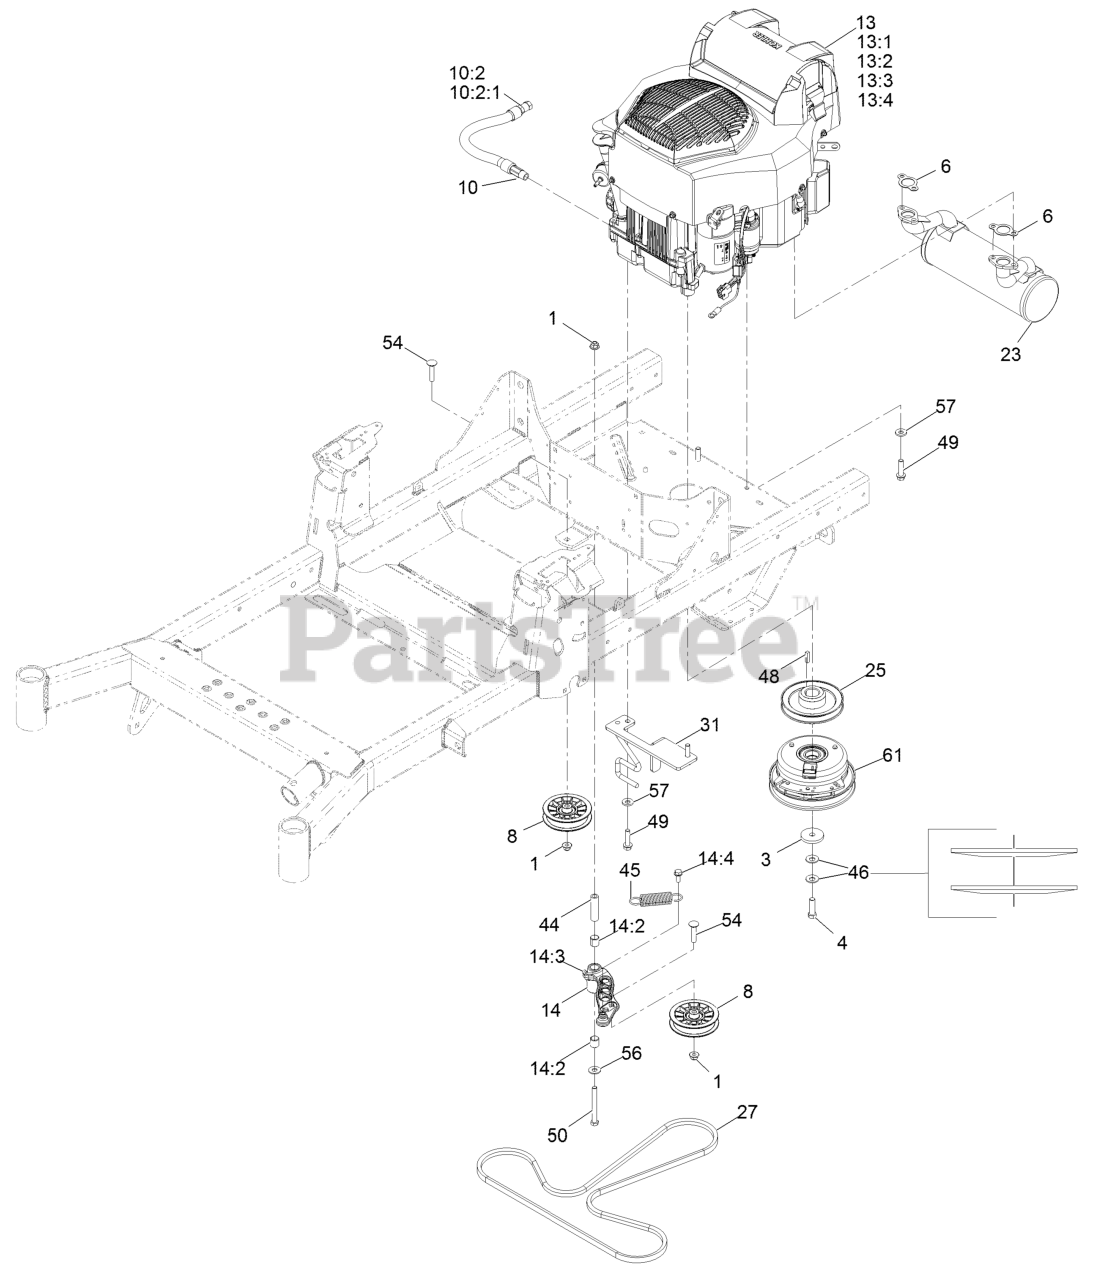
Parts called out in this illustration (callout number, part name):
1	NUT-HF, NI
3	WASHER-CLUTCH
4	SCREW-HH 7/16-20 X 1 1/2 W/LOCTITE
8	PULLEY-FLAT IDLER
10	OIL DRAIN HOSE ASM
10:2	PLUG-HH
10:2:1	O-RING
13:1	Kohler 16 083 01-S Engine Air Filter
13:2	Kohler 52 050 02-S Engine Oil Filter
13:3	Kohler 24 050 13-S Fuel Filter
13:4	Kohler 25 083 04-S Safety Filter
14	IDLER ARM ASM
14:2	SLEEVE-BEARING
14:3	FITTING-GREASE, 90 DEG
14:4	SCREW-THD ROLL, HWH
23	MUFFLER-KOHLER AES
25	SHEAVE (W/HUB)
27	BELT-V
31	ANCHOR-CLUTCH
44	BUSHING-PIVOT, IDLER
45	SPRING-EXTENSION
46	WASHER-SPRING
49	SCREW-HWH
50	SCREW-CARR
54	SCREW-CARR
56	WASHER-FLAT
57	WASHER-BELLEVILLE
